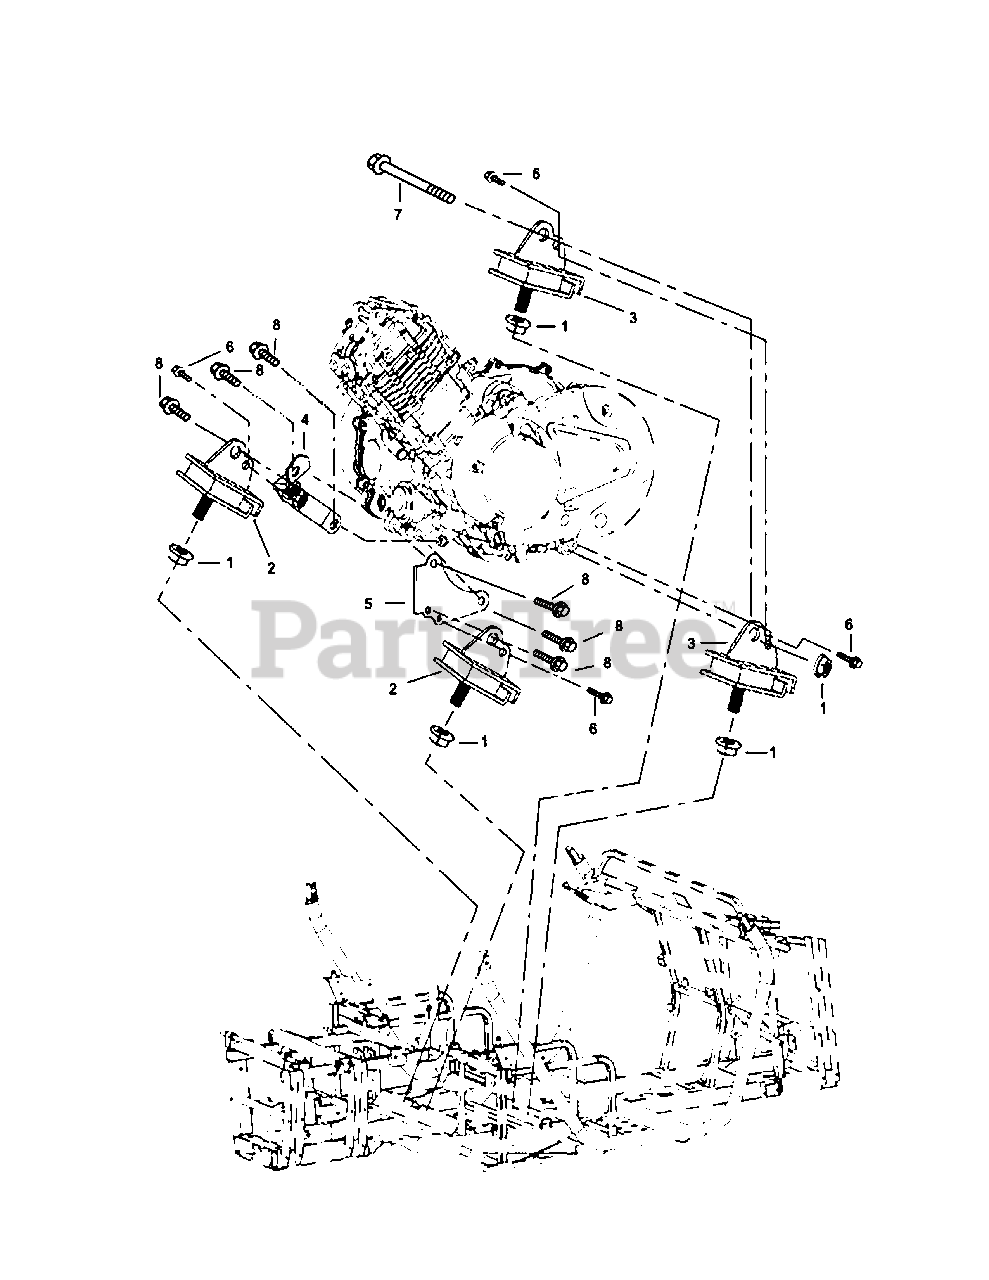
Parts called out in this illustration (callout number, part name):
1	Hexagon flange nut M10×1.25
2	Rear Suspension Support, Engine
3	Front Suspension Support, Engine
4	Right Lower Support ,Engine
5	Left Lower Support, Engine
6	Hexagon Flange Bolt M6×16
7	Hexagon Flange Bolt M10×1.25×170
8	Hexagon Flange Bolt M8×16
